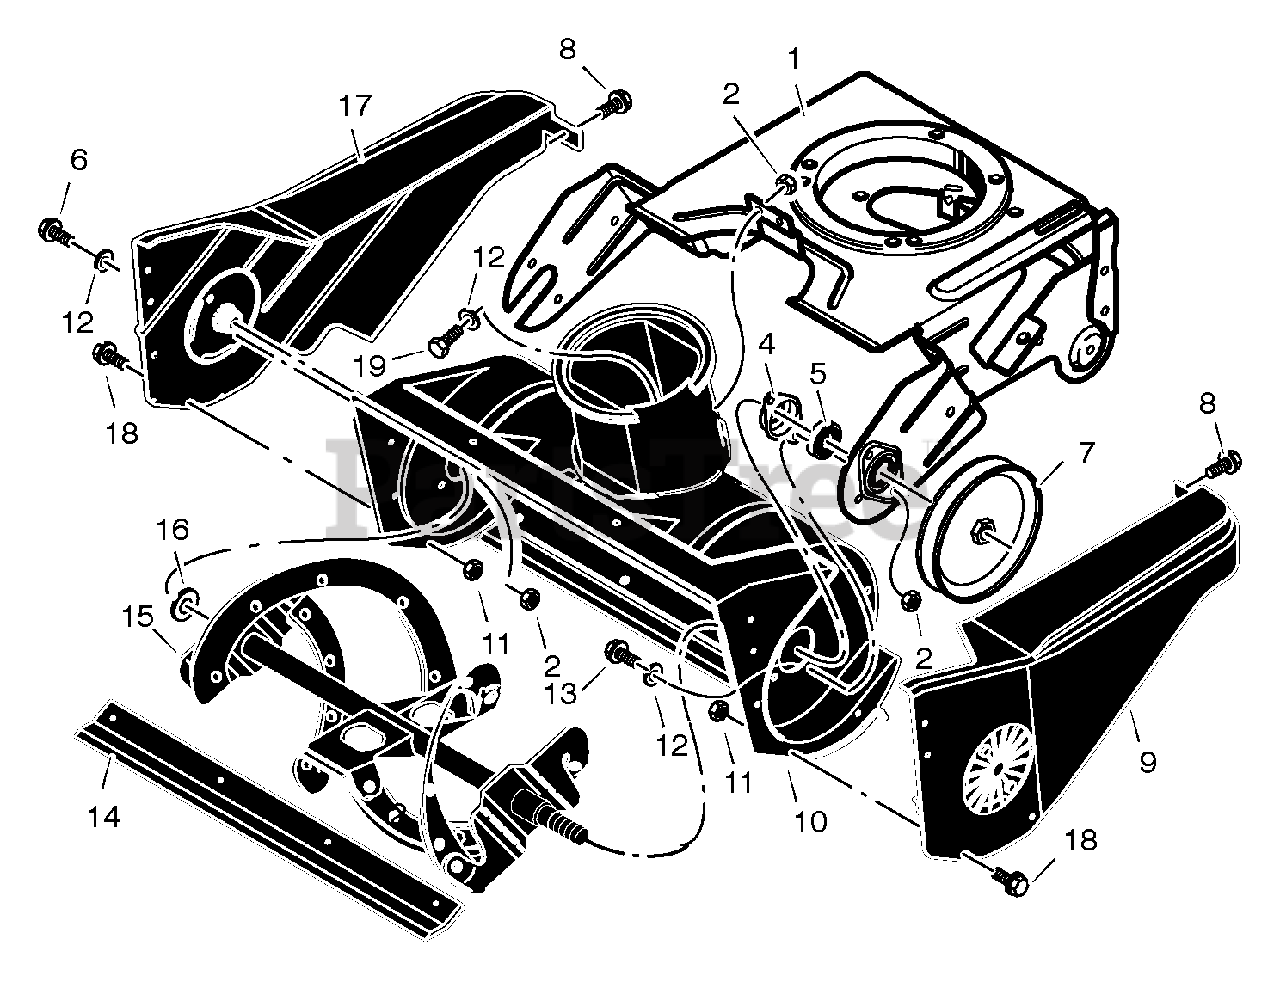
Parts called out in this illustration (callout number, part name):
1	Frame, Motor Box
4	Retainer, Bearing
5	Bearing
7	Pulley, Auger
9	Cover, Left Belt
10	Assembly, Auger Housing
11	Nut
12	Washer
13	Bolt
14	Blade, Scraper
15	Auger Assembly
17	Cover, Right
